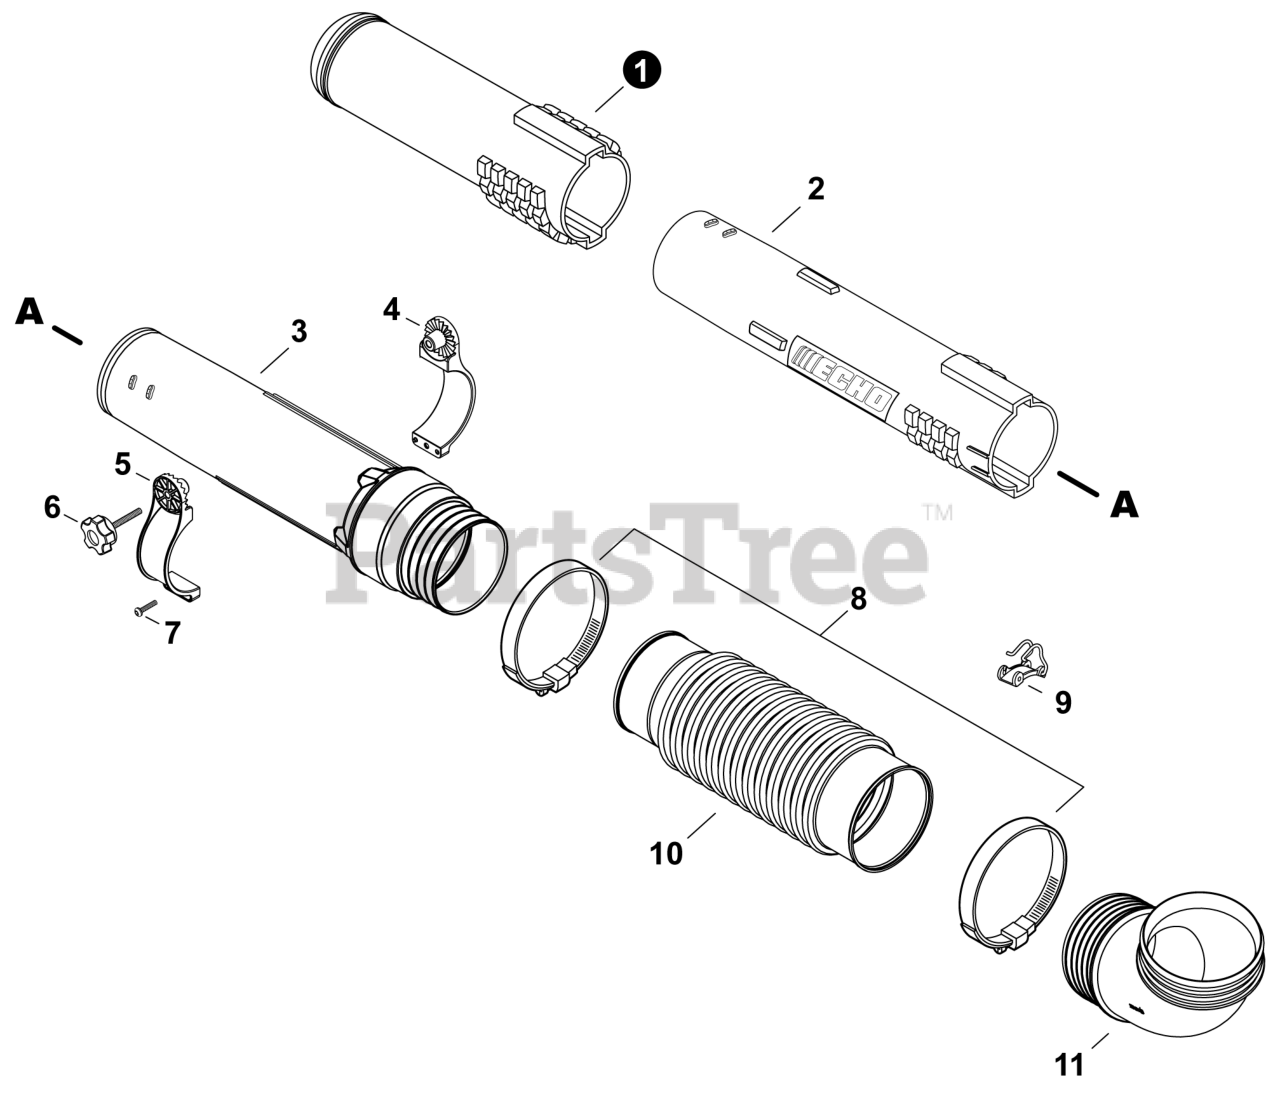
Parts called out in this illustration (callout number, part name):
1	TUBE, BLOWER - NOZZLE
2	TUBE, BLOWER - STRAIGHT
3	TUBE, BLOWER - SWIVEL
4	BRACKET, RIGHT
5	BRACKET, LEFT
6	KNOB, SCREW
7	BOLT, TORX 5x20
8	CLAMP - BAND 77.8 MM / 101.6 MM
9	CLIP, CABLE
10	TUBE, BLOWER - FLEXIBLE
11	TUBE, BLOWER - ELBOW
